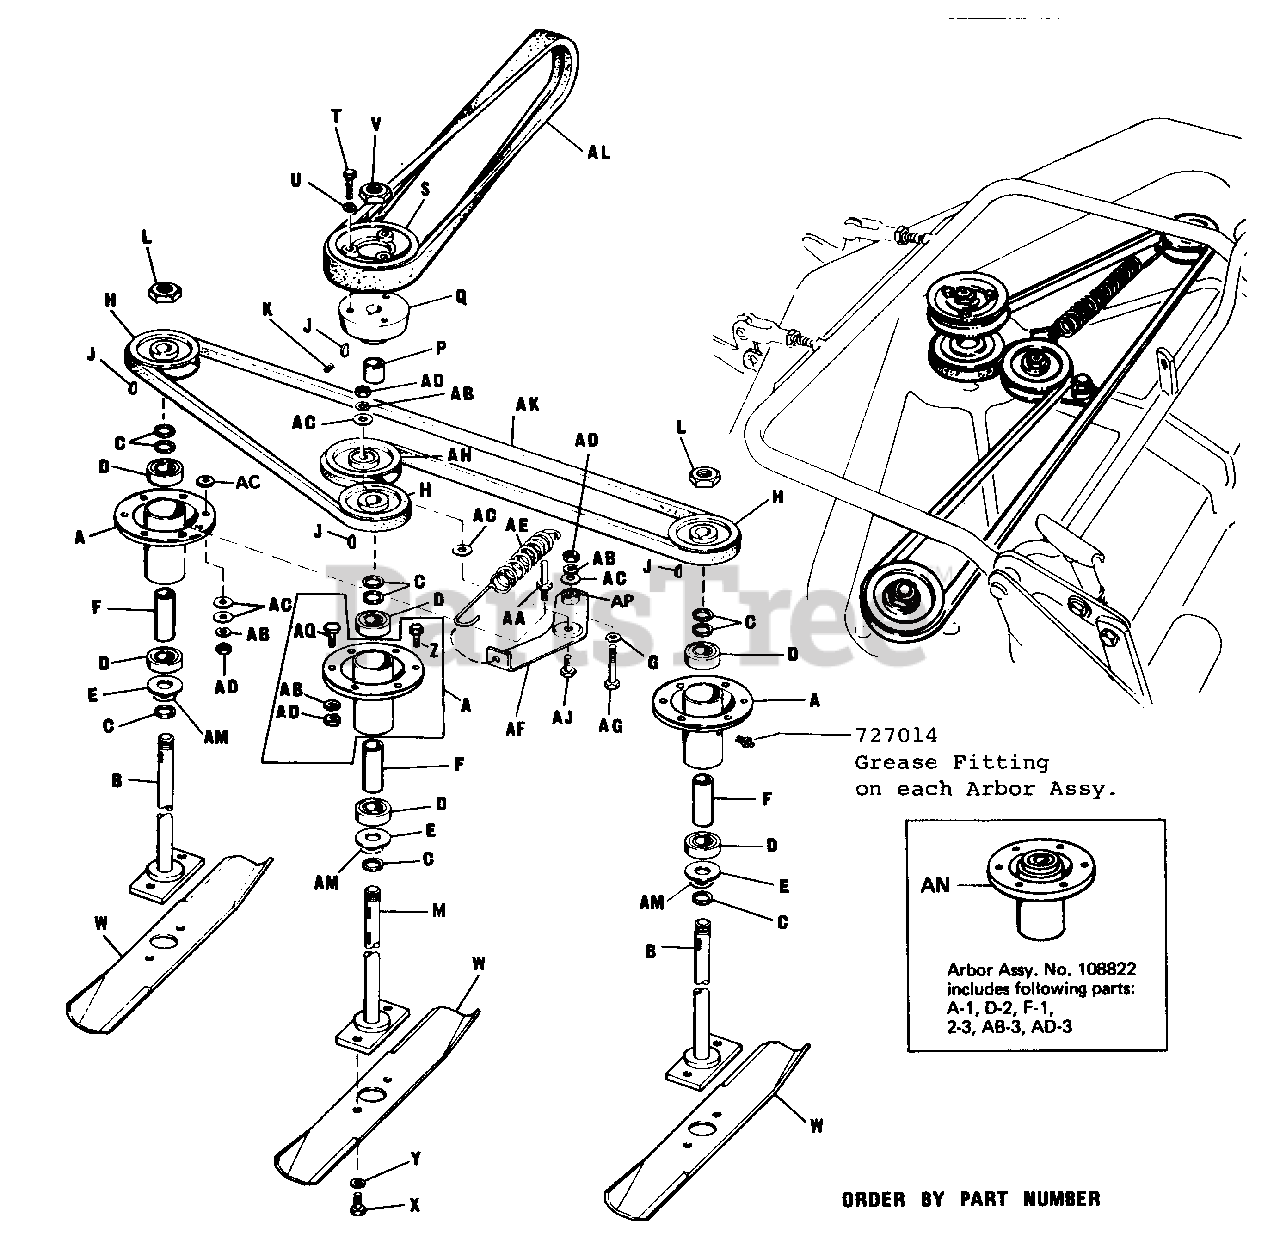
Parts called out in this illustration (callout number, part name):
A	Tube Assembly, Arbor
B	Arbor Assembly
G	Washer, Plain, 3/8"
J	Woodruff Key, #61-3/16" x 5/8" Dia.
L	Hex. Lock Nut, 3/4"-16
M	Arbor Drive Assembly
T	Hex. Cap Screw,5/16-18 x 1-1/2"
U	Lock Washer, 5/16"
V	Hex. Lock Nut, 3/4"-16
W	Knife Blade
X	Hex. Cap Screw, 3/8"-16 x 5/8"
Y	Lock Washer, 3/8"
Z	Screw Hex. Cap, 3/8"-16 NC x 3/4" lg.
AB	Lock Washer, 3/8"
AC	Plain Washer, 5/16"
AD	Full Hex Nut, 3/8"-16
AE	Tension Spring
AF	Idler Lever Assembly
AG	Hex. Cap Screw, 3/8"-16 x 1-3/4"
AH	Idler Pulley
AL	V-BELT, 45"
AN	Arbor Assembly with Bearings and Hardware
AQ	Spec. Hex. Cap Screw,
